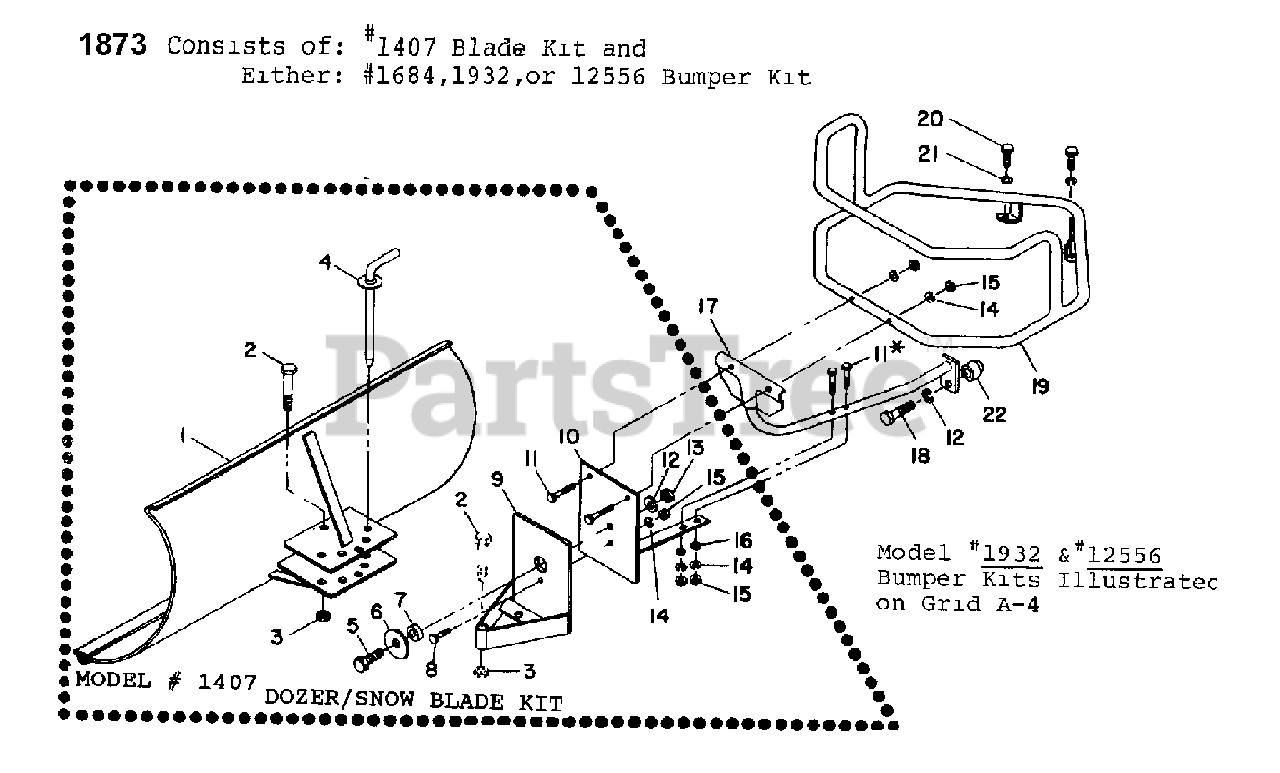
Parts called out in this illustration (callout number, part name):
1	BLADE-dozer/snow blade
2	BOLT-hex. head, 1/2"-13 x 3"
3	LOCKNUT-hex., 1/2"-13
4	PIN-index, blade angle adjustment
5	BOLT-hex. head, 1/2"-13 x 1 1/2"
6	WASHER-plain, 1/2"
7	BUSHING
8	SCREW-hex. head, 5/16"-18 x 1 1/4"
9	BRACKET-swivel ("A" frame)
10	BRACKET-dozer/bumper mounting
11	SCREW-hex. head, 5/16"-18 x 1 3/4"
12	LOCKWASHER-1/2"
13	NUT-hex. 1/2"-13
14	LOCKWASHER-5/16"
15	NUT-hex., 5/16" x 18
16	WASHER-plain, 5/16" S.A.E.
17	BRACE-bumper bottom
18	BOLT-hex. head, 1/2"-13 x 2"
19	BUMPER-wraparound
20	BOLT-hex. head, 3/8"-16 x 1"
21	LOCKWASHER-3/8"
22	SPACER-for bottom brace
1407	Blade Kit
1684	Bumper Kit
1932	Bumper Kit
12556	Bumper Kit
